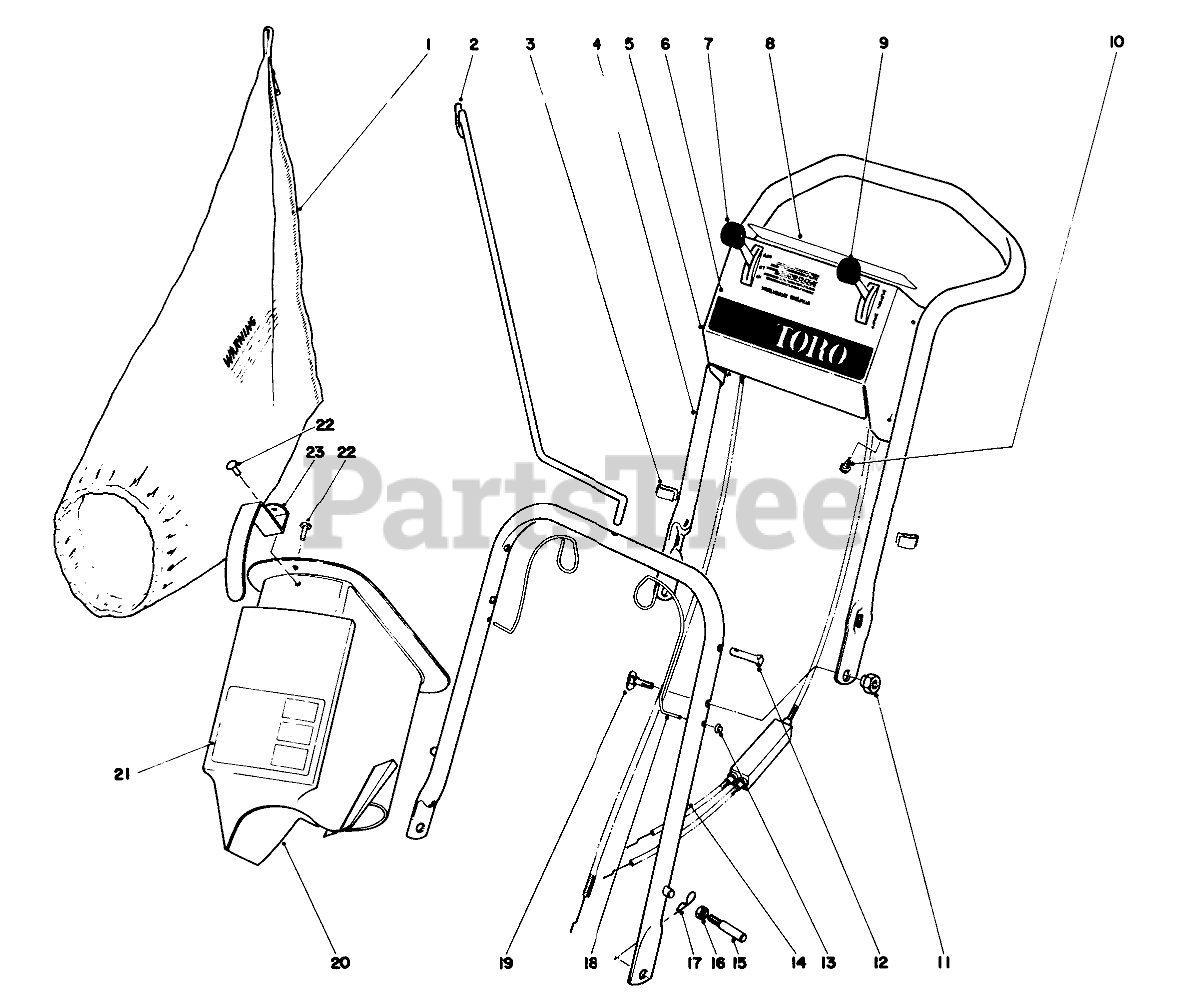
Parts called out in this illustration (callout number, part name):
1	Grass Bag
2	Bag Rod
4	UPPER HANDLE
5	Control Plate
6	Decal Control Plate
7	Control Throttle
8	Decal Safety Instructions
9	Control Traction
10	SCREW-HWHTF
11	Pivot Nut
12	Pin Latch
14	Lower Handle
15	HANDLE PIN
16	Nut
17	PIN-COTTER, HAIR
18	Spring Latch
19	HANDLE SCREW
20	Grass Chute (Incl. Ref. #21-23)
21	Decal Instructions
22	RIVET 3/16 X 7/16
23	Handle Chute
